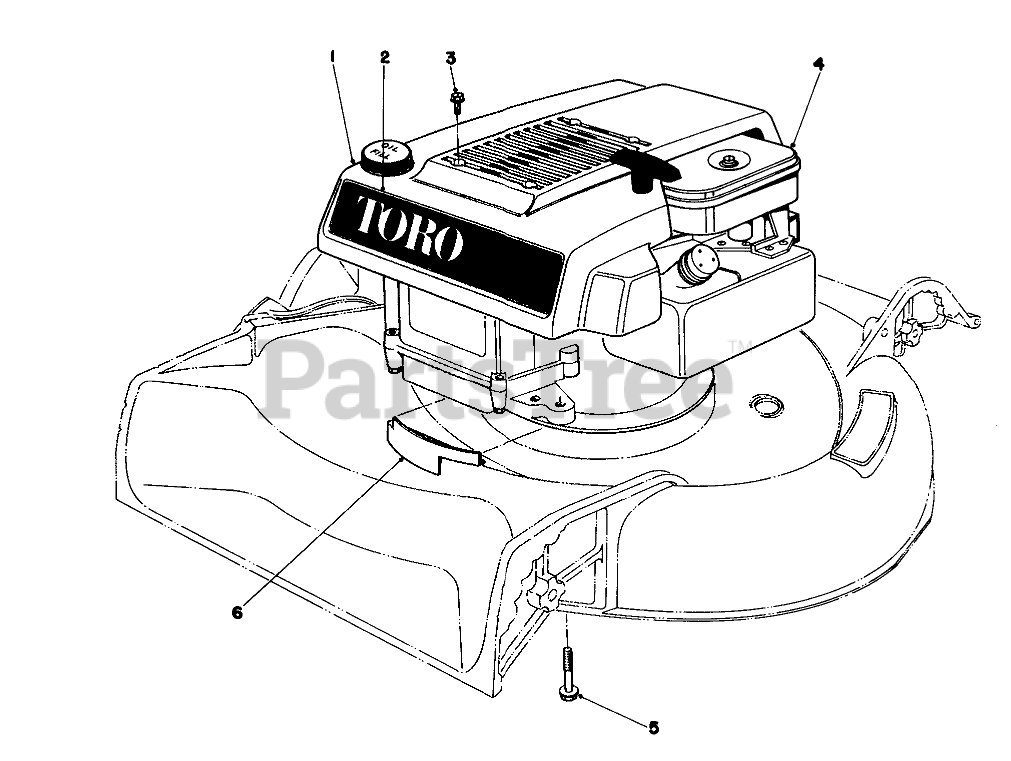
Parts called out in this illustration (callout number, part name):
1	Shroud
2	Decal-Toro
3	8X1/2 SELF TAP SCREW
4	Engine
5	3/8-16 X 2-3/4 CAPSCR
6	HOUSING CAP
